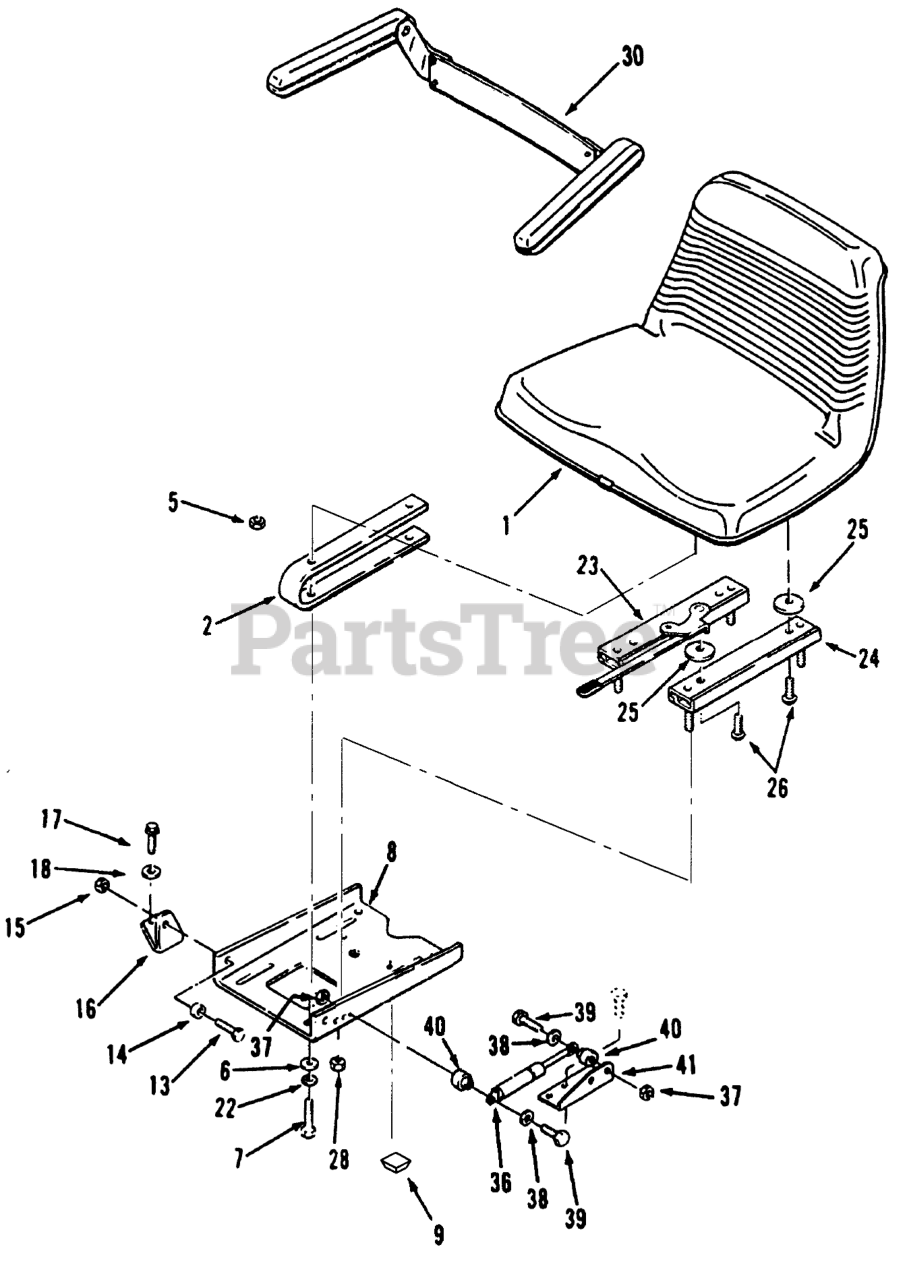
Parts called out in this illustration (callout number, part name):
1	Seat
2	Seat Spring
5	NUT-HEX
6	WASHER-PLAIN
7	SCREW-HH
8	Plate-SeatPivot
9	BUMPER SJ5514 BLACK
13	HHCS
14	BUSHING
15	NUT-LOCK, NI
16	Bracket-Pivot RH
17	Bolt
18	WASHER 5/16 SAE
22	WASHER-LOCK
23	Adjuster-Seat
24	ADJUSTER-R.H. SEAT
25	SPACER-NYLON
26	Screw
28	NUT-HEX
30	KIT-ARMREST
34	NUT-LOCK, NI
36	GAS SPRING
37	NUT-LOCK, NI
38	WASHER-FLAT
39	SCREW-HH
40	SPACER
41	BRACKET-CYLINDER R
